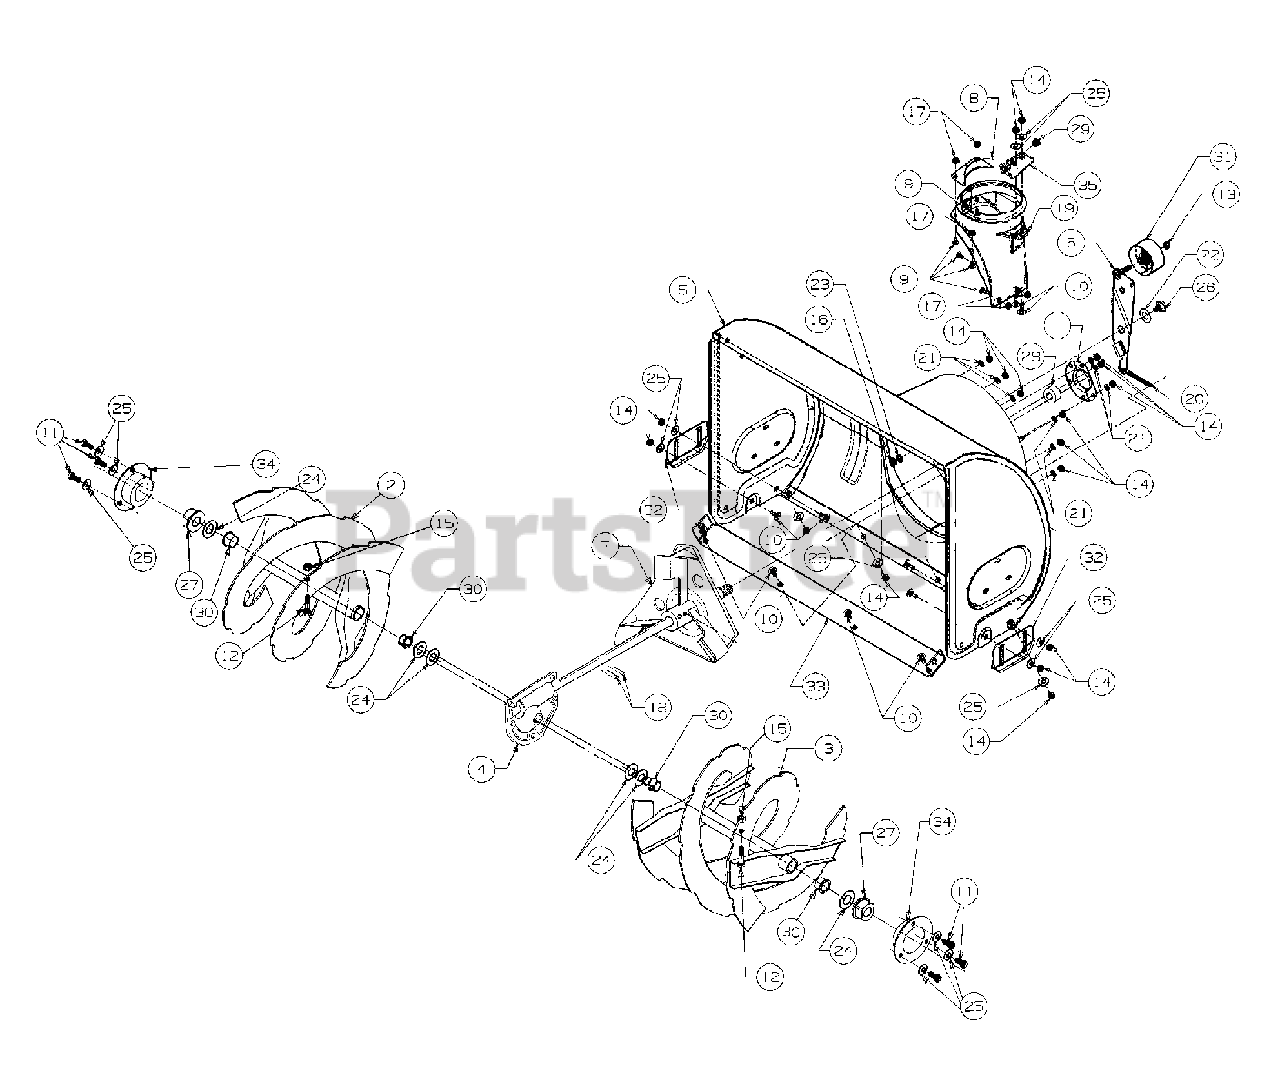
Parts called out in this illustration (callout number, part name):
1	Housing-Bearing
2	Spiral Assembly - L.H. 26"
3	Spiral Assembly - R.H. 26"
4	Gear Assembly 26"
7	Impeller Assembly
9	Screw - Carriage
10	Screw - Carriage
11	Screw - Hex
12	Shear Bolt
13	Nut - Hex Lock
14	Nut - Hex
15	Nut - Hex
16	Nut - Hex
17	Nut - Hex Lock
18	Pin - Spring
19	Adapter - Chute
20	Spring
21	Washer - Lock
22	Washer - Flat
23	Washer - Lock
24	Washer - Flat
25	Washer - Bell
26	Screw - Shoulder
27	Bearing - Flange
28	Bearing - Ball
29	Bushing - Plastic
30	Bushing-Flange
31	Idler - Flat
32	Shoe - Slide
33	Shave Plate 26"
